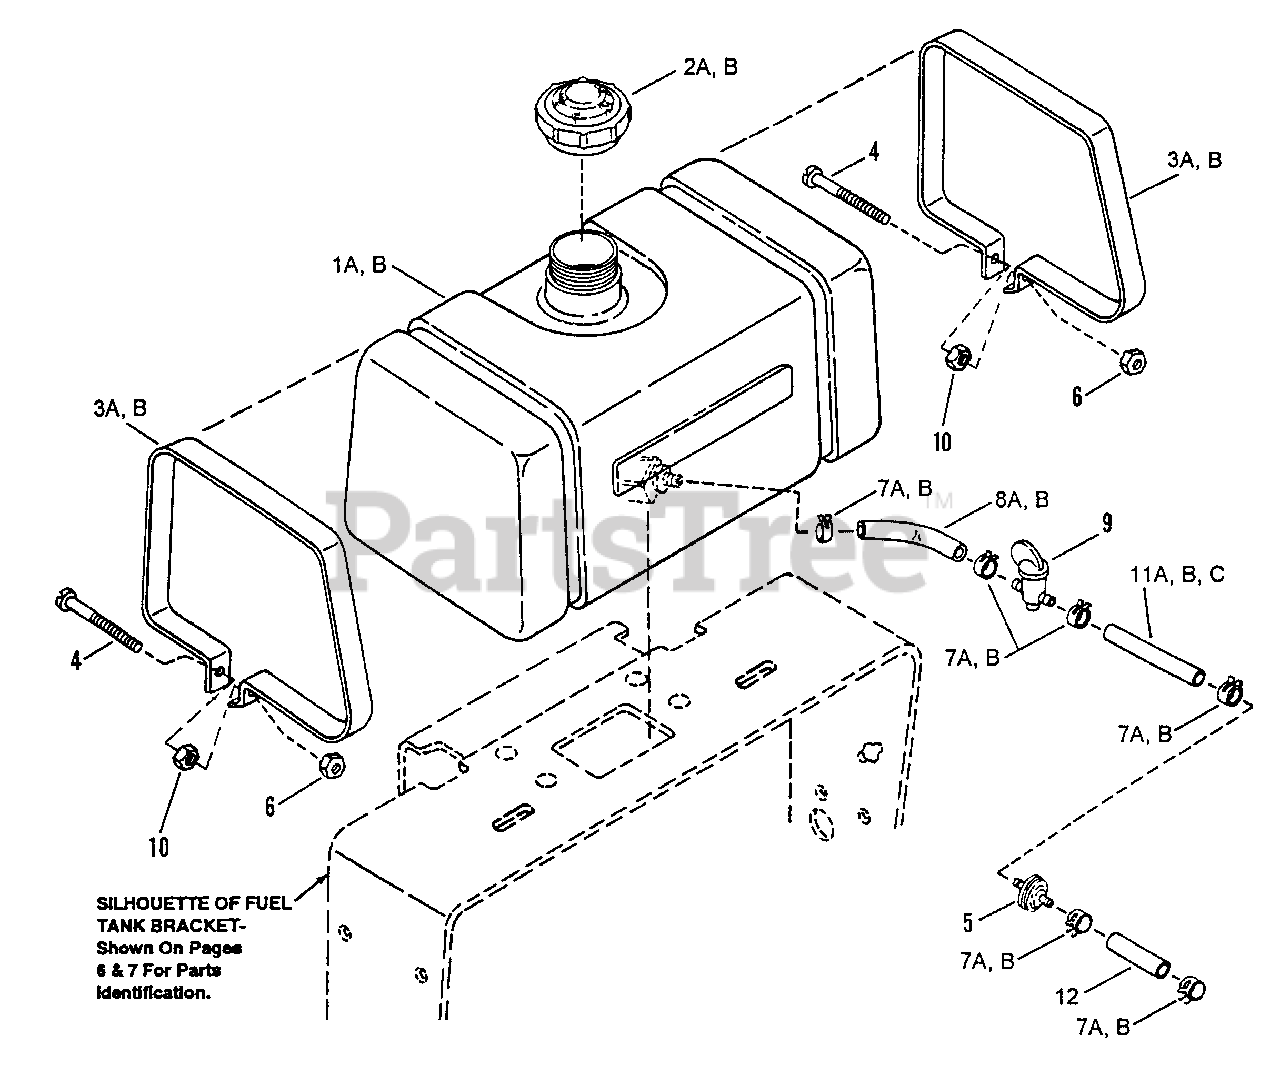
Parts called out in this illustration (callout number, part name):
1A	TANK, Fuel
1B	TANK, Fuel
2A	CAP, Fuel
2B	CAP, Fuel
3A	STRAP, Fuel Tank
3B	STRAP, Fuel Tank
4	SCREW, #10-24 x 2-1/2" Machine Head Phillips
5	FILTER, Fuel, in-Line
6	NUT, #10-24 Nyloc
7A	CLAMP, Fuel Hose
7B	CLAMP, Fuel Hose
8A	HOSE, Fuel, 10" Long
8B	HOSE, Fuel, 8-1/2" Long
9	VALVE, Fuel Shut-Off
10	NUT, 10-24 Keps
11A	HOSE, Fuel, 10" Long
11B	HOSE, Fuel, 6-1/2" Long
11C	HOSE, Fuel, 8-1/2" Long
12	HOSE, Fuel, 3-1/2" Long
